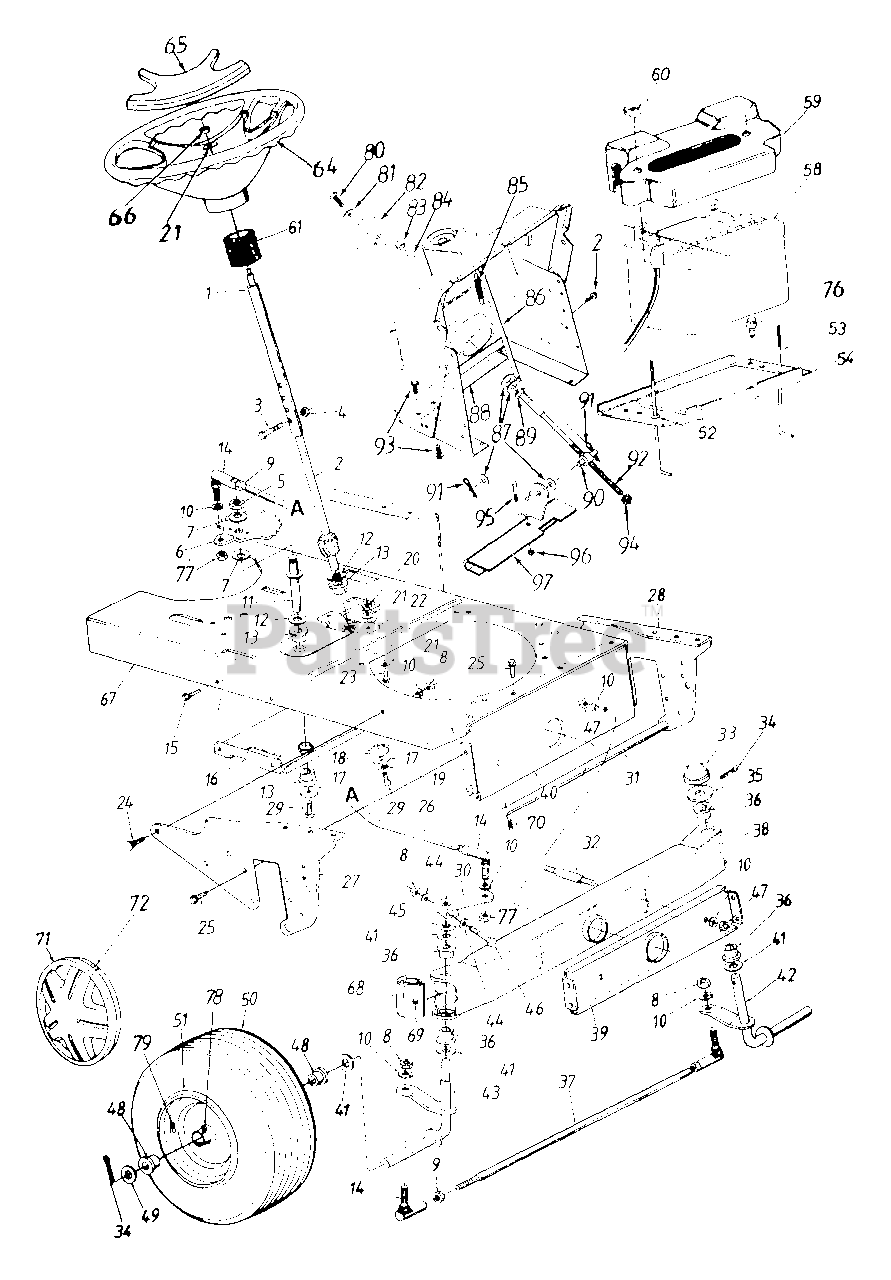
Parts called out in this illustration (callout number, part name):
1	Steering Column Ass'y.
2	Lower Steering Shaft
3	Hex Bolt 1/4-20 x 1.31" Lg.
4	Hex L-Nut 1/4-20 Thd.
5	Hex Nut 5/8-18 Thd.
6	Steering Gear Segment
7	Bell-Wash. 5/8" I.D. x 1.25" O.D.
8	Hex Nut 3/8-24 Thd.
9	Hex Jam Nut 3/8-24 Thd.
10	L-Wash. 3/8" I.D.
11	Steering Gear Segment Shaft
12	Fl-Wash. .64" I.D. x 1.24" O.D.
13	Hex Flange Brg. .63" I.D.
14	Ball Joint Ass'y.
15	Hex Wash. Hd. TT-Tap Scr. 1/4-20 x .5" Lg.
17	Fl-Wash. .33" I.D. x 1.25" O.D.
18	Spacer .985" I.D. x 1.25" O.D.
19	L-Wash. 5/16" I.D.
20	Hex Nut 5/16-24 Thd.
21	Bell-Wash. .345" I.D. x .88" O.D.
24	Ribbed Neck Bolt 3/8-24 x .8" Lg.
25	Hex Wash. TT-Tap Scr. 5/16-18 x .62" Lg.
26	Steering Drag Link
30	Steering Arm Ass'y.
31	Deck Connecting Rod
32	Pivot Bar Shld. Bolt 3/8-16 x 5/8" Lg.
33	Cap
34	Cotter Pin 5/32" Dia.
36	Flange Brg. .757" 1.0.
37	Tie Rod 20.25" Lg.
38	Pivot Bar Assy.
41	Fl-Wash. .76" I.D. x 1.49" O.D.
42	Front Axle Ass'y. - L.H.
43	Front Axle Ass'y. - R.H.
44	Bowed Washer
45	Spacer .755" I.D. x 1.25" O.D.
46	Hex Bolt 3/8-24 x 2.25" Lg.
47	Hex Nut 3/8-16 Thd.
48	Ball Brg. .75" I.D.
49	Fl-Wash. .71" I.D. x 1.5" O.D.
53	Battery Hold Down Rod
54	Battery Plate
58	Battery
59	Battery Cover
60	Wing Nut Plastic 1/4-20 Thd.
61	Steering Bellow
64	Steering Wheel
65	Steering Wheel Insert
66	Hex L-Nut 5/16-24 Thd.
69	Grease Fitting
70	Internal Cotter Pin
72	Spring Clip
76	Hex Wash. B-Tap Scr. 1/4" x .62" Lg.
77	Hex Jam L-Nut 3/8-24 Thd.
78	Grease Fitting
79	Air Valve
80	Hex Cap Bolt 1/4-20 x .75" Lg.
81	Bell-Wash. .265" I.D. x .75" O.D.
82	Plastic Knob 3" Dia.
83	Spacer .38" I.D. x .5" O.D.
84	Ball Plunger
85	Ext. Spring 4.62" Lg.
86	Indicator Strip Ass'y.
87	Fl-Wash. 3/8" I.D. x .87" O.D.
90	Adjustment Ferrule
91	Hairpin Clip
92	Height Adjustment Rod
93	Hex Wash. TT- Tap Scr. 5/16-18 x .62" Lg.
94	Hex L-Nut 3/8-8 Twin Thd.
95	Hex Bolt 1/4-20 x 1.5" Lg.
96	Hex L-Nut 1/4-20 Thd.
